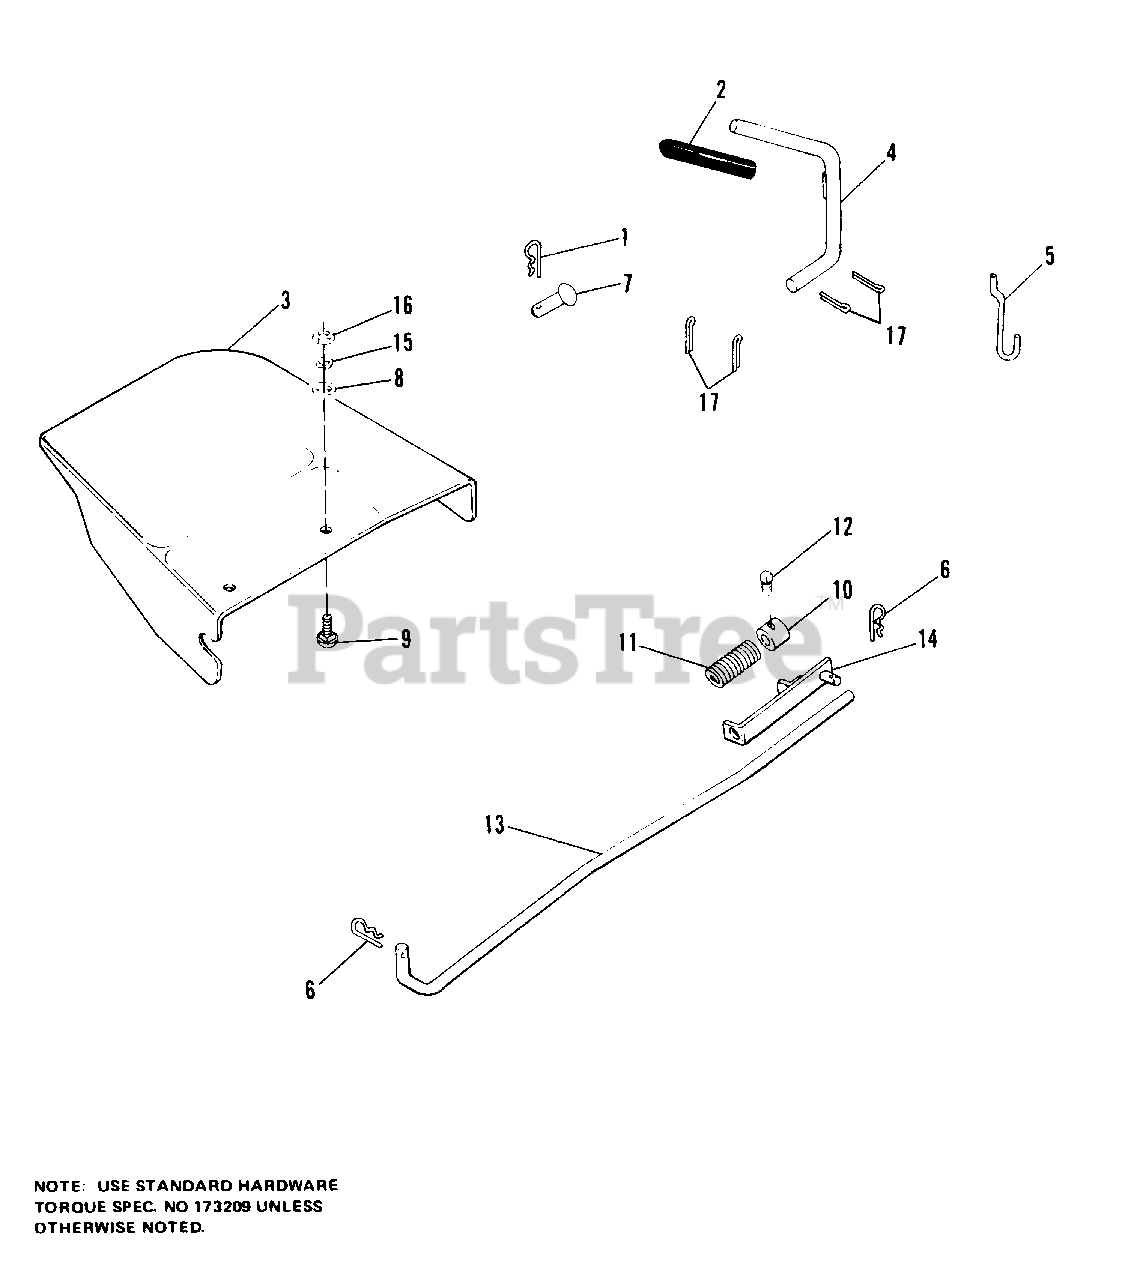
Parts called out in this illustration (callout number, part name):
1	PIN, Quick
4	LEVER, Height Control
5	ROD, Lift Hook
6	PIN, Quick
8	WASHER, 3/8
9	BOLT, Carriage, 3/8-16 x 3/4
10	COLLAR, Set
12	SETSCREW, Cup Pt., 1/4-20 x 3/8, Gr. 8
14	GUIDE ASSY., Rod
15	LOCKWASHER, 3/8
16	NUT, Hex, 3/8-16
17	PIN, Cotter, 1/8 x 1
